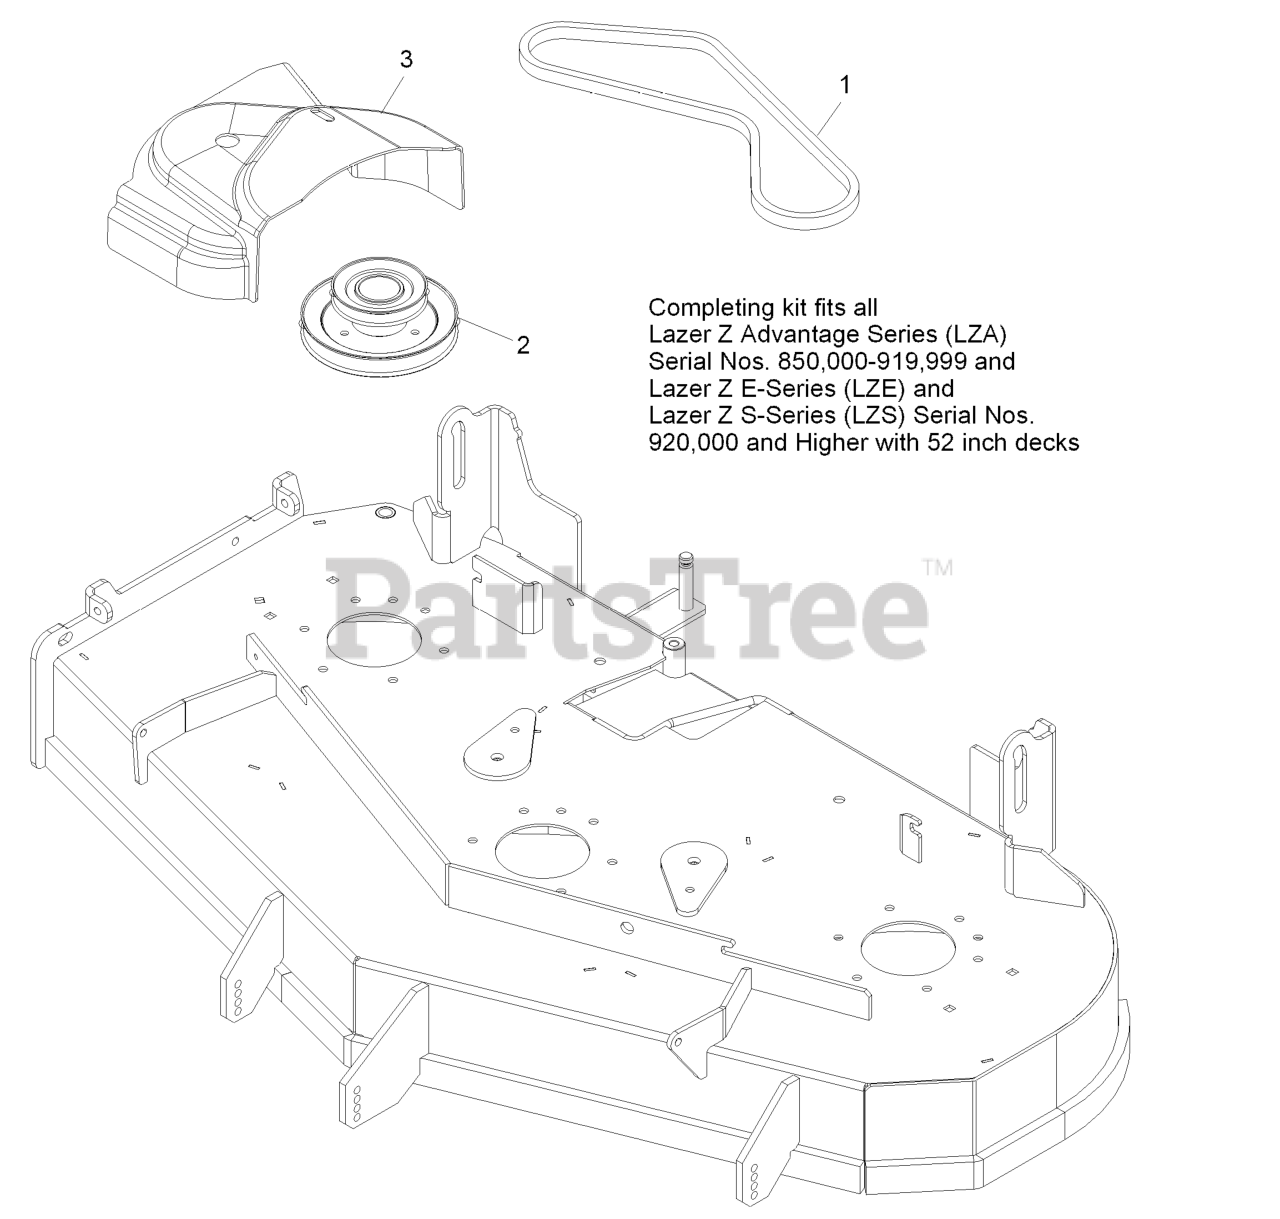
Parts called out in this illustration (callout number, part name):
1	BELT, BLOWER 52"DECK
2	JACKSHAFT,UV DRIVE 524 SP
3	COVER,BELT UV 52
